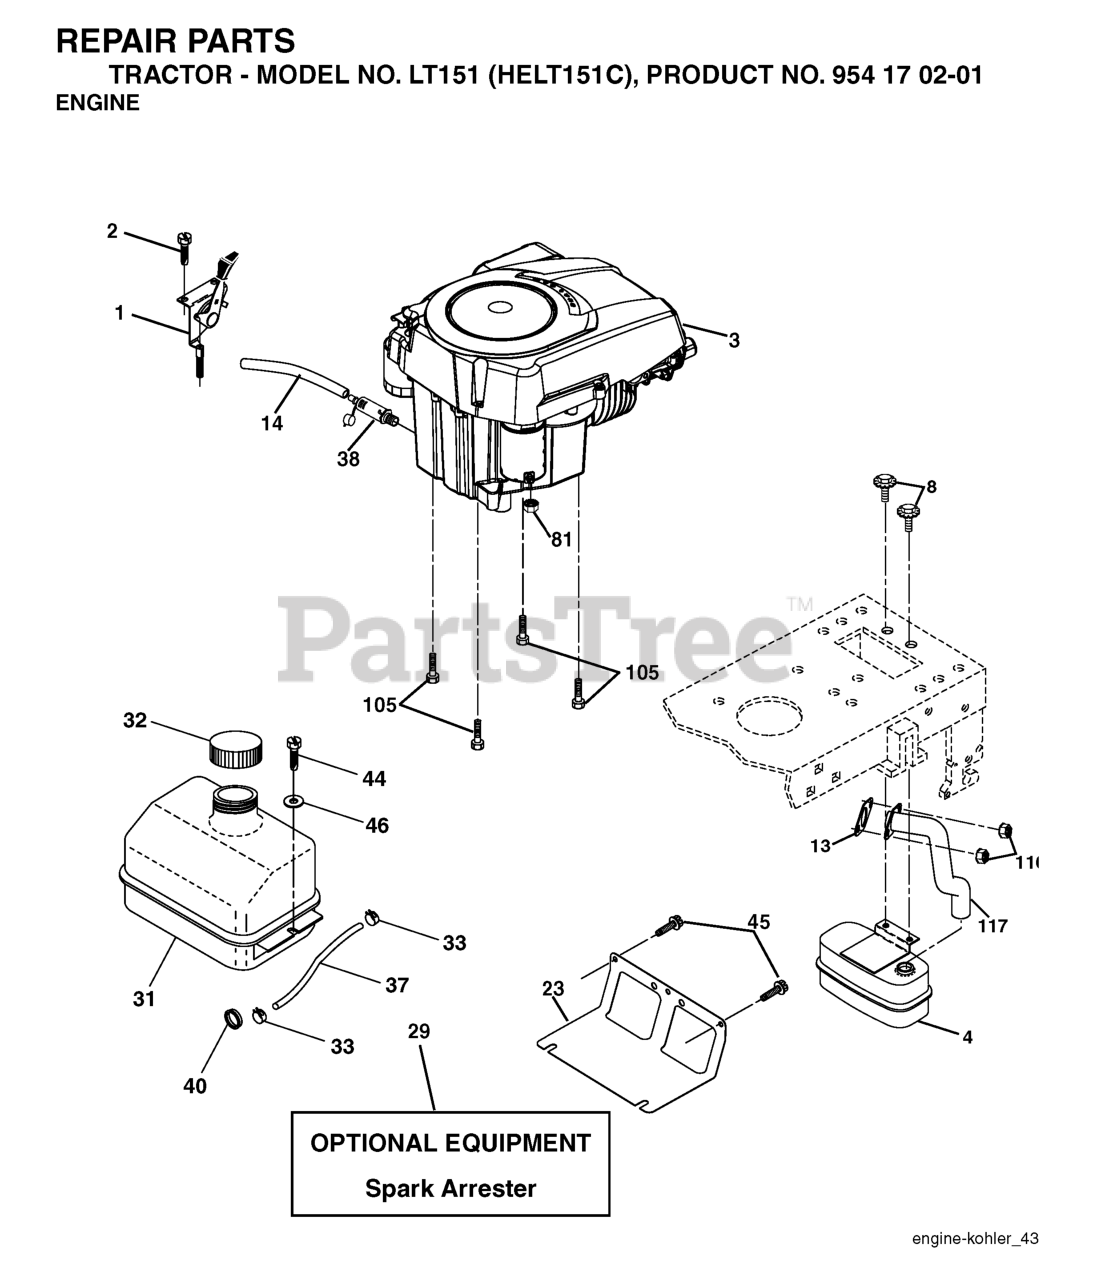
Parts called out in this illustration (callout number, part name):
1	CONTROL.THROTTLE.LT/YT
2	SCREW
4	MUFFLER.SINGLE.CYL.KOHL/B&S
8	BOLT.5/16-18UNCX3/4 W/SEMS.BLK
13	GASKET.EXHAUST.KOHLER
14	TUBE, DRAIN OIL ASM.
23	SHIELD.BROWNING.DBR.GUARD
29	KIT.SPARK ARRESTOR 794945 B&S
31	TANK.ASM.FUEL.FRONT.W/CAP
32	FUEL CAP
33	HOSE CLAMP
37	LINE.FUEL.20
38	PLUG DRAIN OIL EASY
40	BUSHING.SNAP.NYL.BLK.
44	SCREW HEXWSHR 1/4-20X3/4
45	SCREW, 3/8-16X3/4
81	NUT
105	SCREW 3/8-16X1
116	NUT.HEX.FLANGE.TOPLOCK
117	RP.TUBE.EXHAUST.KOHL.COURAGE
